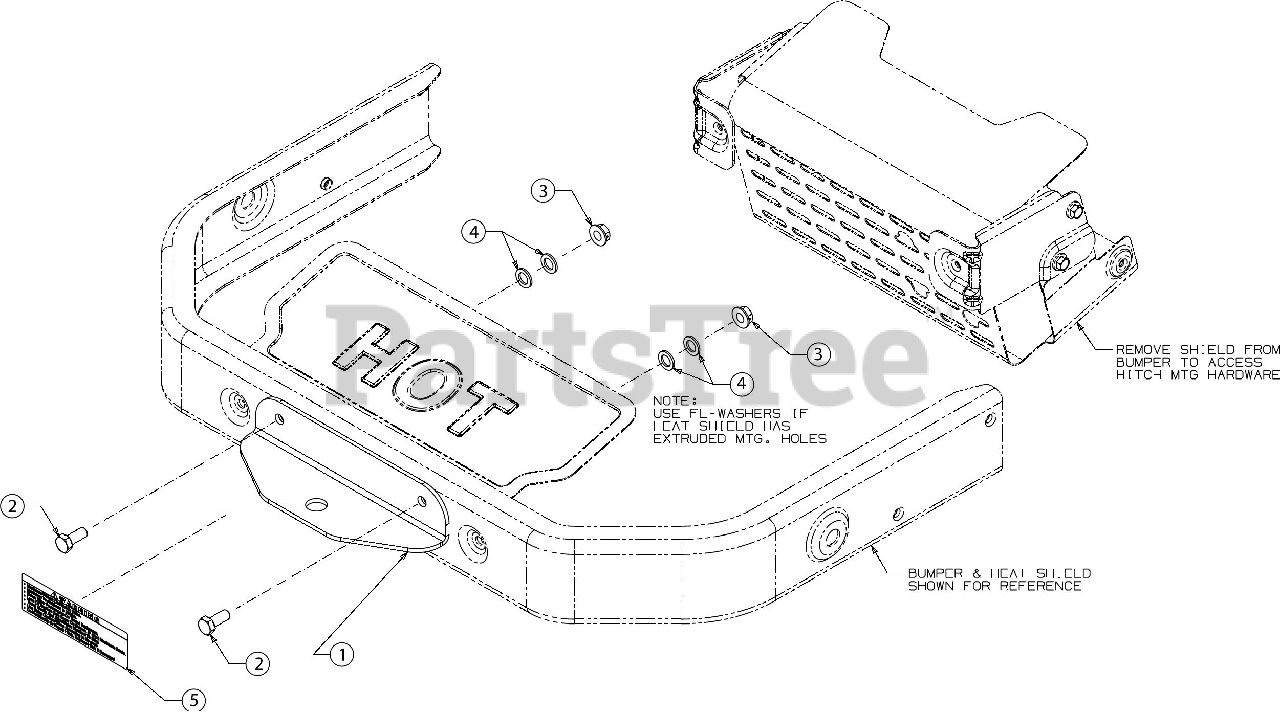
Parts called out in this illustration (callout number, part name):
2	SCREW 5/16-18 x .75 GR5
3	FLANGE NUT
4	FLAT WASHER
5	LABEL-TOWING WARNING
